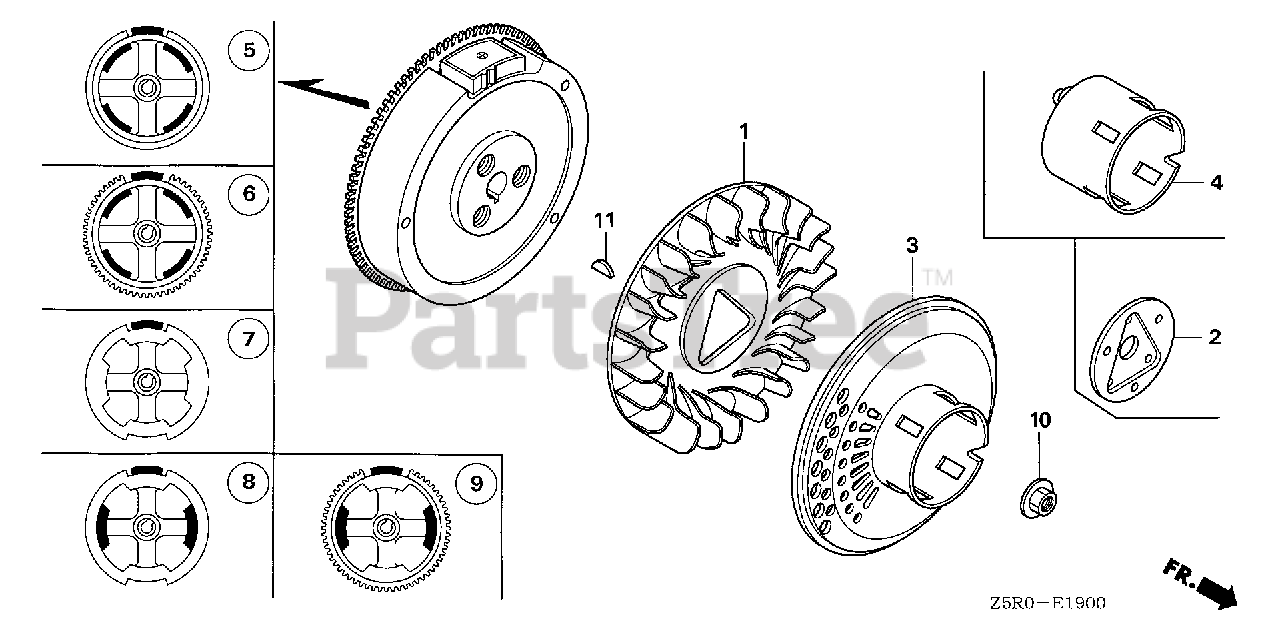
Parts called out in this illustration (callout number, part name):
1	FAN, COOLING
3	PULLEY, STARTER (SCREEN GRID)
9	FLYWHEEL (SEL-LAMP)
10	NUT, SPECIAL (16MM)
10	NUT, SPECIAL (16MM) (1)
11	KEY, SPECIAL WOODRUFF (25X18)
